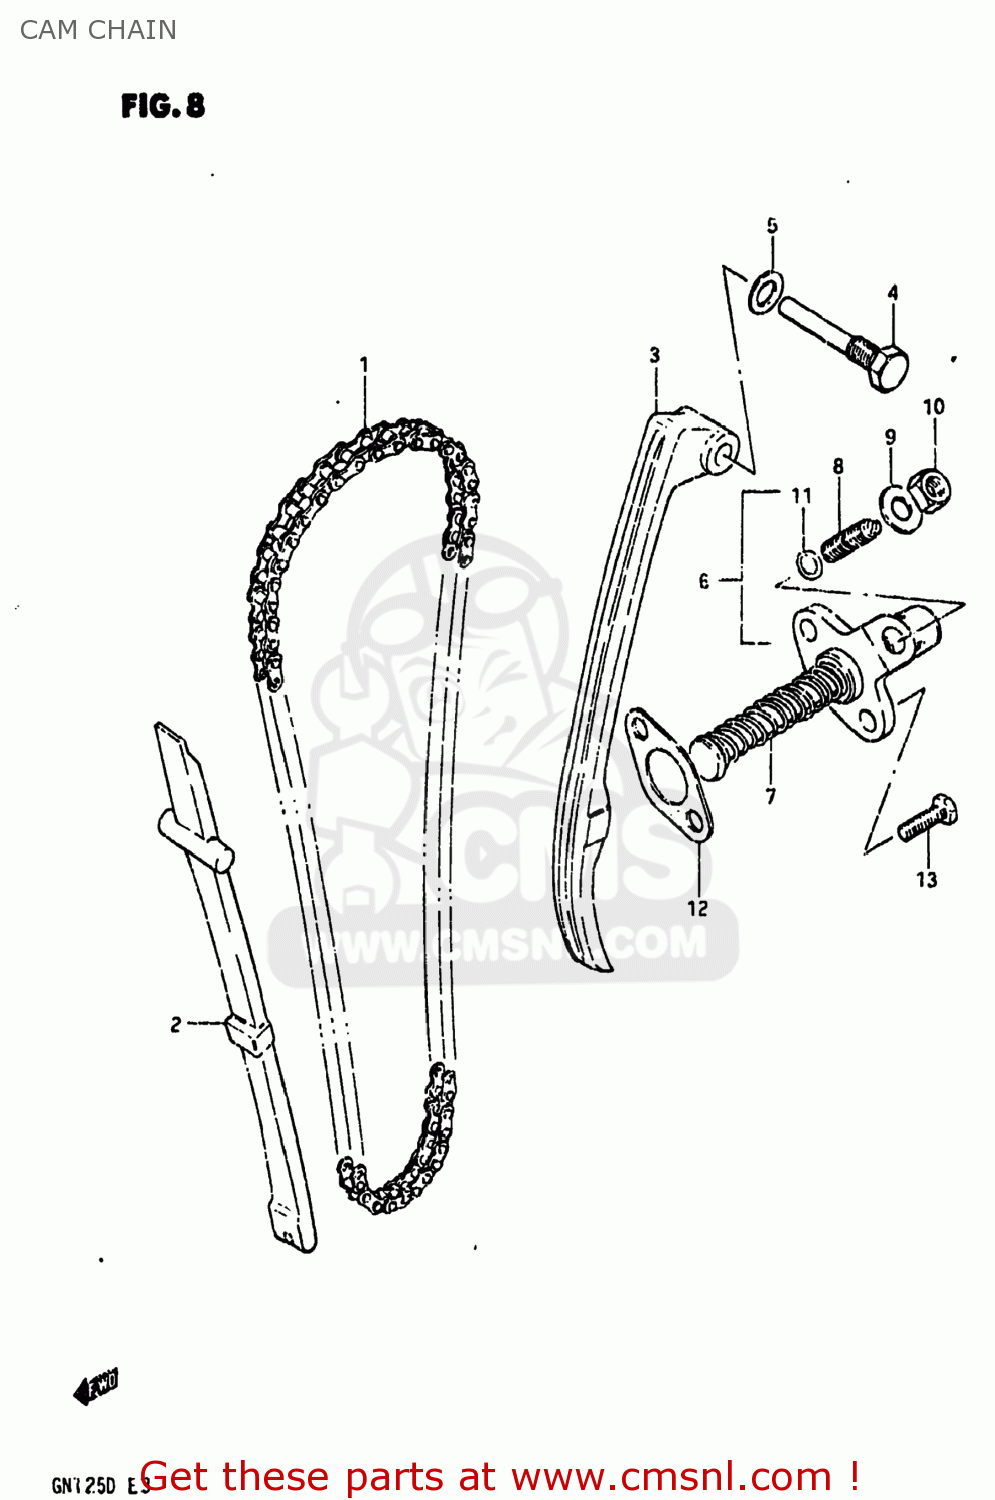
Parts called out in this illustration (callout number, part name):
1	CHAIN,CAMSHAFT DRIVE
2	GUIDE,CAM CHAIN
3	TENSIONER,CAM CHAIN
4	BOLT,CAM CHAIN TENSIONER
5	GASKET 8.2X14X1 (NAS)
6	ADJUSTER ASSEMBLY,TENSIONER
7	SPRING
8	SCREW
9	WASHER
10	NUT
11	O RING(D:1.9,ID:5.7)
12	GASKET,TENSIONER ADJUSTER (NAS)
13	BOLT
